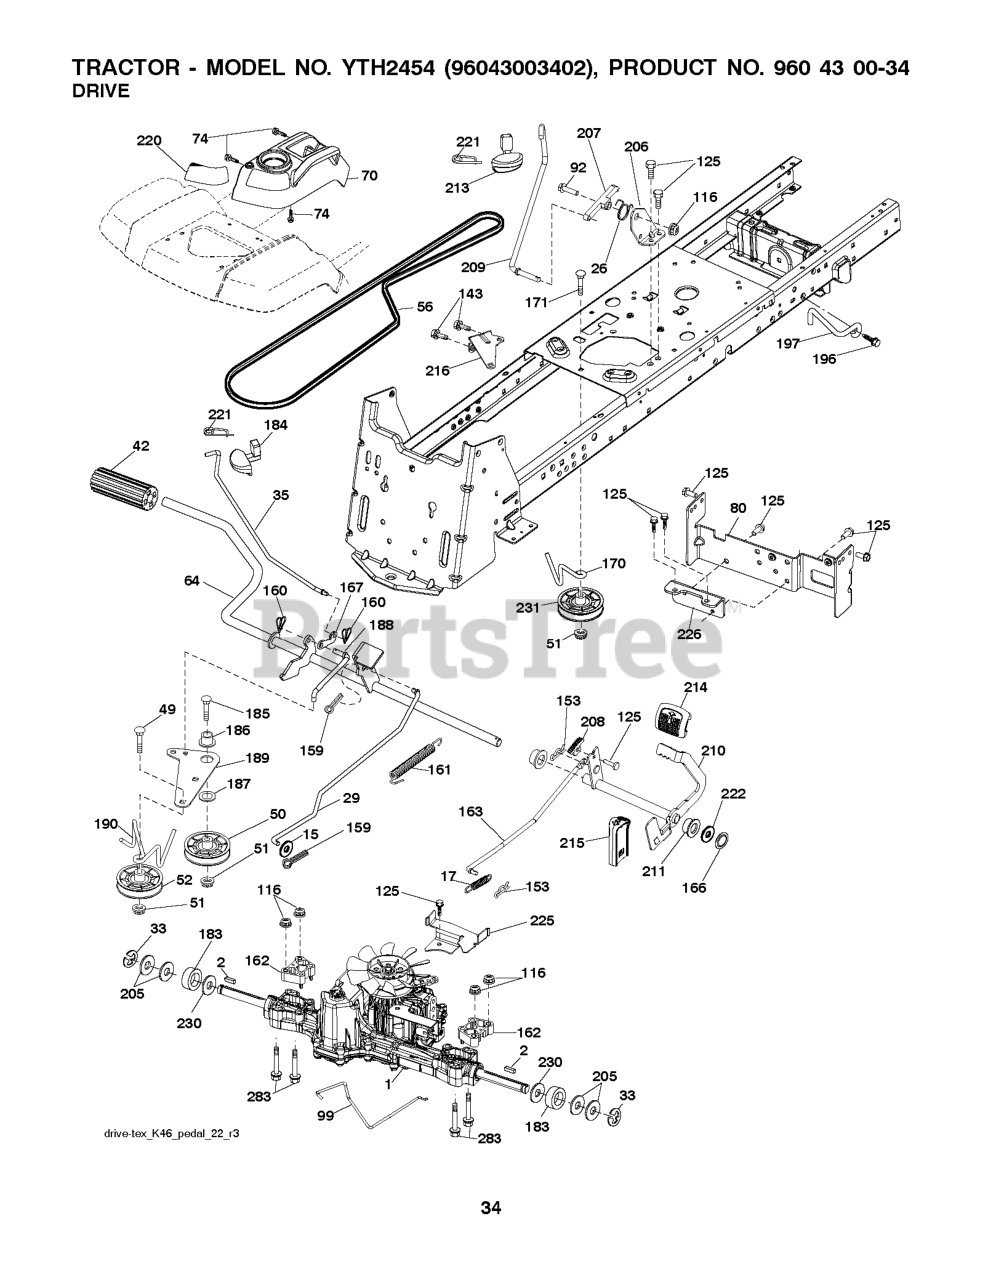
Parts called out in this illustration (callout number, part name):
1	TRANSAXLE, TUFFTORQ K46
2	SQUARE KEY
15	WASHER
17	SPRING.BRAKE.K46.GREEN
26	SPRING.RETURN.CRUISE
29	ROD.BRAKE.K46
35	ROD.BRAKE.PARKING.GT.H
42	PEDAL COVER T
50	IDLER.FLAT.910.OFFSET
51	NUT LOCK FLG 3/8-16 UNC
52	IDLER.V-GROOVE.910.OFFSET
56	V-BELT.MOWER.92.40.42/K46
64	SHAFT.ASM.PEDAL.BRK.CNTR
70	RP CONSOLE.ASM.PCH.W/TB
74	SCREW.HI-LO.CONSOLE
80	STRAP TORQUE
92	BOLT
99	ROD.SPRING.BYPASS.K46.TEX.GT
116	NUT LOCK HEX FLANGE 5/16-18
125	SCREW
143	Screw 5/16-18 x 1/2 Hex, Self Tapping 5/16-18 x 1/2
153	RETAINER M
159	COTTER PIN
160	RETAINER CLIP
161	SPRING, RETURN LT
162	SPACER TRANS
163	ROD.CONTROL.PEDAL.K46
166	NUT.PUSH.625.2006
167	LATCH.BRAKE.SPRING
170	KEEPER.CENTER SPAN.1.688
183	SPACER AXLE
184	HANDLE.PARKG.BRK.HUSQ X667
186	SPACER.RETAINER
187	WASHER 12/32X2X10GA
188	RP.LINK.CLUTCH.GROUND.DRIVE
189	BELLCRANK.GROUND.DRIVE.TEX.
190	KEEPER.BELLCRANK.DRIVE
196	SCREW 3/8-16X1
197	BRKT.ANIT-ROTATION.CLUTCH
206	BRKT.MOUNT.LATCH.CRUIS
207	LATCH.CONTROL.CRUISE
208	GEAR.SECTOR.CONTROL.CR
209	ROD.CONTROL.CRUISE.GT.
210	ROCKER.ASM.PEDAL.CONTR
211	BEARING.NYLON
213	KNOB.CONTROL.CRUSIE.HU
214	PEDAL.FORWARD.TEX.GT.4
215	PEDAL.REVERSE.TEX.GT.4
216	BRACKET.PULLEY.IDLER.W/TEX
220	REFLECTOR.RH.TEX GT
221	RETAINER.SPRING.CLIP.H
222	WASHER
225	KEEPER.BELT.TRANSAXLE.K46
226	BRACKET.MOUNT.TORQUE.K46.TLT
230	WASHER.HARDENED
231	IDLER.V-GROOVE.1.688.OFFSET
283	HEX BOLT, 5/16-18 X 4.25 GR. 5
